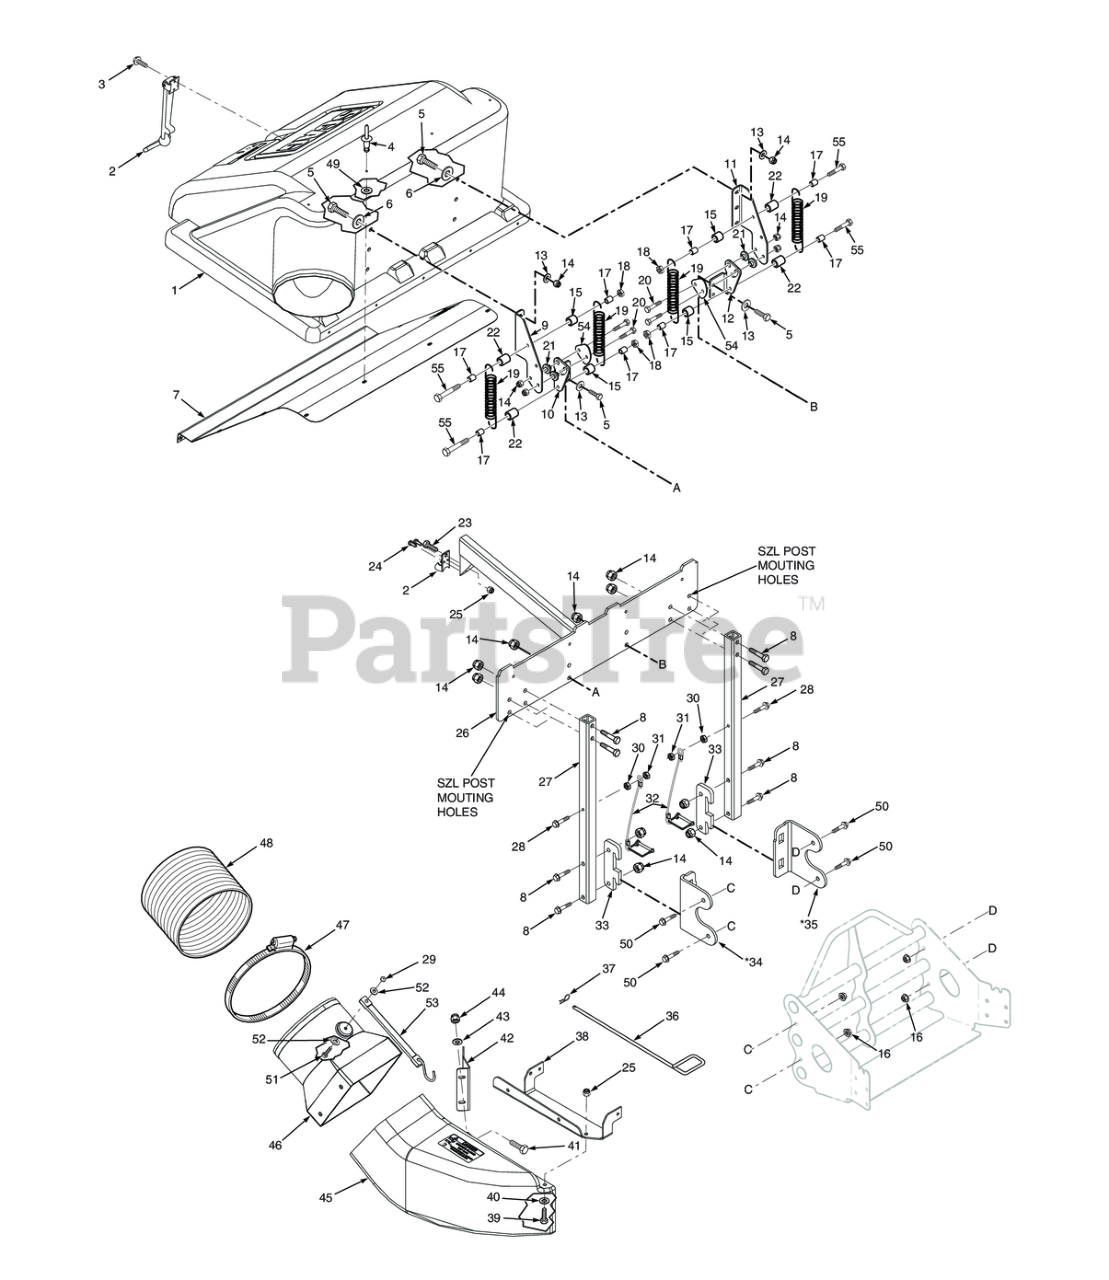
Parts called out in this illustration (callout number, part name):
1	Hood Assembly
2	Latch, Hopper
3	Screw, #10-32 x 3/4"
3	Flatwasher, 3/8-.196 x .496 x .048
3	HEX NUT, ELASTIC STOP LOCK # 10-32
4	Pop Rivet, 3/16 x .652"
5	Bolt, Hex Head 3/8-16 x 1-1/4", Kawasaki FX / FS
6	Flatwasher, 3/8-.406 x 1-1-1/2 x 7 Gauge
7	Screen, GC Hood
8	Bolt, Hex Head 3/8-16 x 2-1/4" - 61"
9	Hinge, Upper RH
10	Hinge, Lower RH
11	Hinge, Upper LH
12	Hinge, Lower LH
13	Flatwasher, 3/8-.391 x .938 x .105
14	HEX NUT, ELASTIC STOP LOCK, 3/8-16
15	SPACER, J-PULL ROD
16	NUT, 3/8-16 SERRATED FLANGE HEX HEAD
17	Spacer, Deck Assist
18	Bolt, Hex Head 3/8-16 x 1" Ser. Flg.
19	Spring, Hood Hinge
20	Bolt, Hex Head, 3/8-16 x 1-1/2"
21	Bushing, Hopper Pivot
22	Spacer
23	BOLT, SERRATED FLANGE HEX HEAD 5/16-18 X 3/4"
24	Rivot, 3/16 x .402 POP
25	HEX NUT, ELASTIC STOP LOCK, 5/16-18
26	Frame Weldment, Bag Support
27	Tube, Grass Catcher Mount
28	Bolt, Hex Head 1/4-20 x 0.63"
29	HEX, NUT, ELASTIC STOP LOCK, 1/4-20
30	NUT, 1/4-20 SERRATED FLANGE HEX HEAD
31	Bolt, Hex Hd. 1/2-13 x 9-1/2"
32	Snap Pin Assembly w/Lanyard
33	Latch, GC-SFZ
34	Bracket, GC Mount RH
35	Bracket, GC Mount LH
36	Latch Pin, GC Chute
37	HAIR PIN, .08 DIAMETER X 1-3/16"
38	Bracket, GC Boot - 36" Deck
38	Bracket, GC Boot - 48", 52" & 61" Deck
39	Bolt, Heax Head 5/16-18 x 1" (48V / 52V)
40	Flatwasher, 5/16-.344 x .688 x .065 (48V / 52V)
41	Capscrew, Hex Head 1/4-20 x 1"
42	Baffle, Boot Deflector - 36" Deck
42	Baffle, Boot Deflector - 48" Deck
42	Baffle, Boot Deflector - 61" Deck
43	Flatwasher, 1/4" (.312 x .750 x .065")
44	HEX, NUT, ELASTIC STOP LOCK, 1/4-20
45	Boot Assembly
46	Adapter, Blower GC-STC,
47	Clamp, 8-5/8" Max Dia. (61")
48	Hose, 8.00" Dia. x 56.00" Long
49	Flatwasher, 3/16 (.196 x .469 x .048)
50	Bolt, Hex Head, 3/8-16 x 1 Gr. 5
51	SERR. FLG. HEX HEAD CAPSCREW, 5/16-18 X 3/4
52	Flatwasher, 1/4" (.312 x .750 x .065")
53	Rubber Strap 7-3/4"
54	Guard, GC Hinge
55	Bolt, Hex Head 3/8-16 x 4.00
